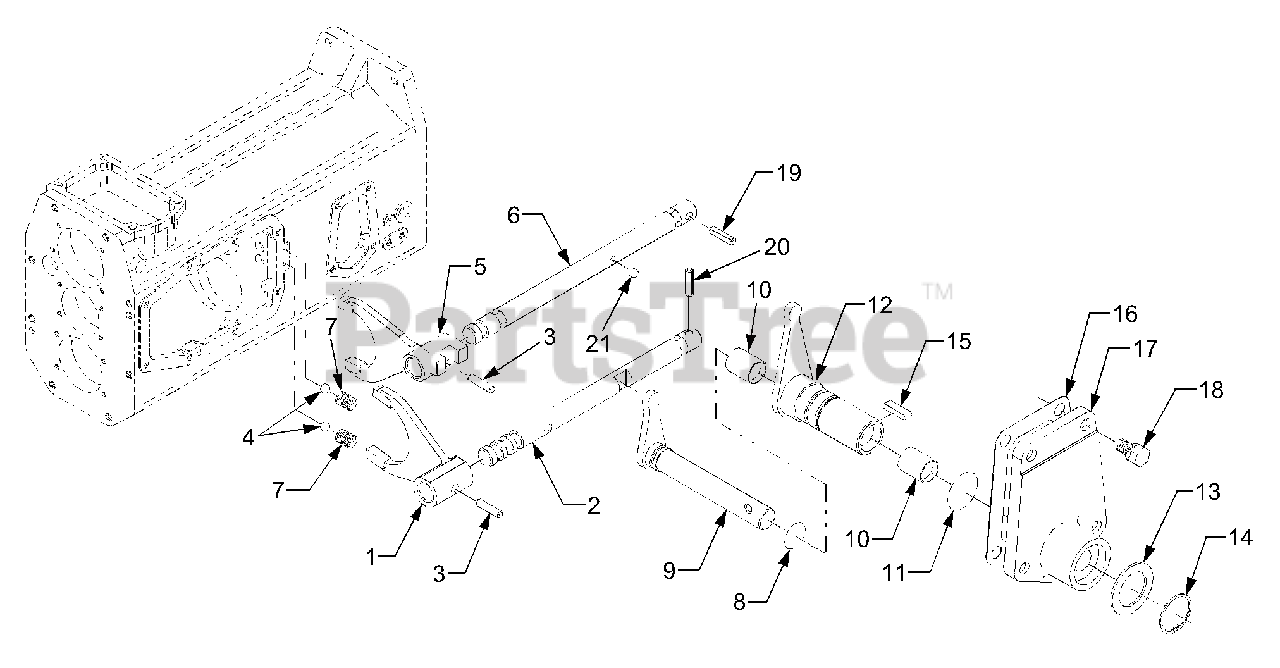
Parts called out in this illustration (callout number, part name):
1	Fork, Shift (Hi-Low Shift)
2	Rod, Fork (Hi-Low Shift)
5	Fork, Shift (Creep)
6	Rod, Fork (Creep)
9	Arm, Shift (Hi-Low Shift)
12	Arm, Shift (Creep)
